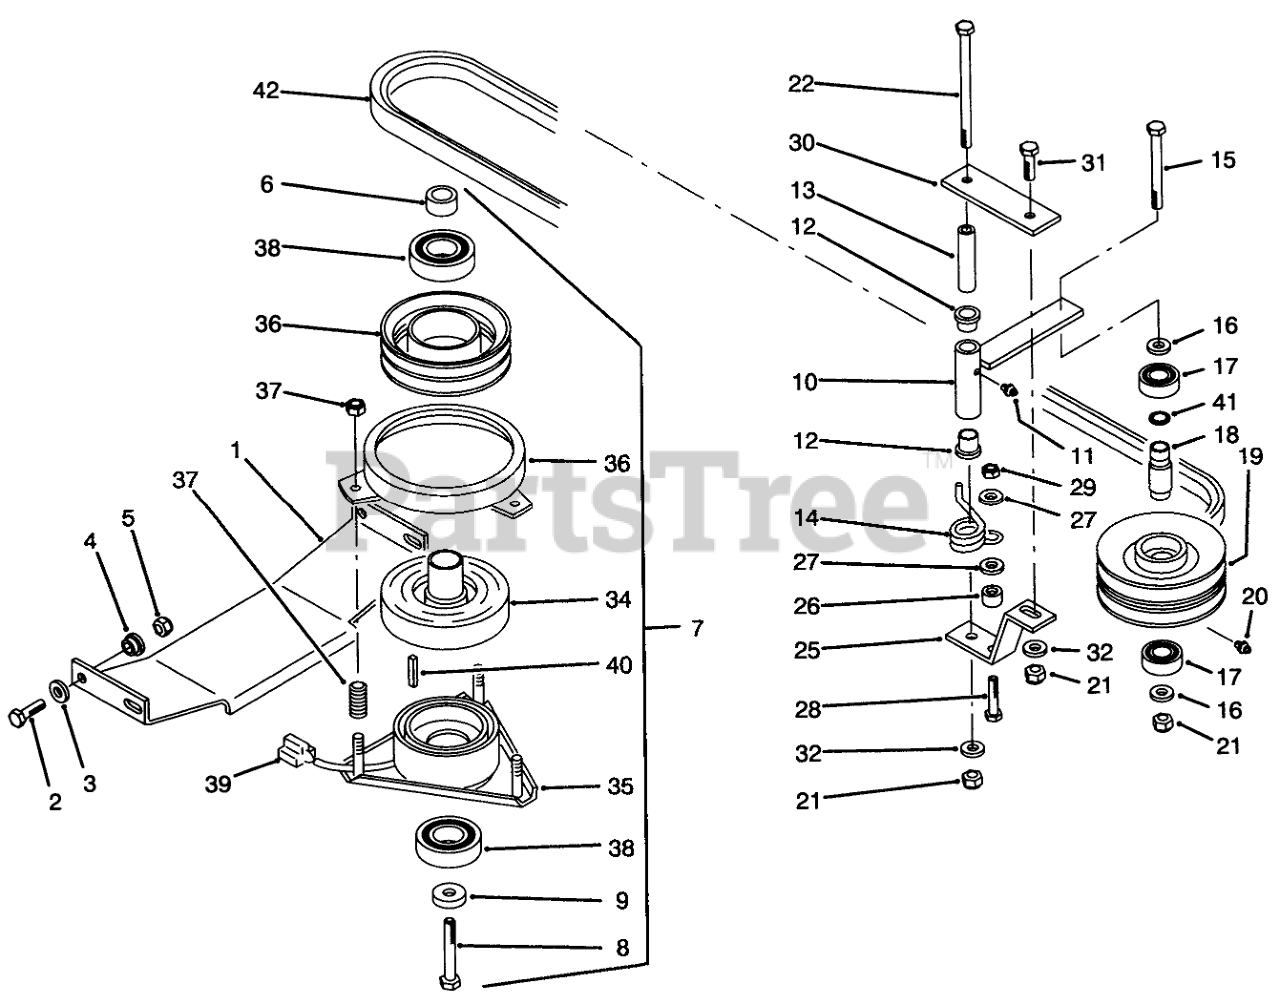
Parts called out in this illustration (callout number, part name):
1	BRACKET CLUTCH ST R
2	SCREW-HH
3	WASHER-PLAIN
4	BUSHING
5	NUT-LOCK, NI
6	SPACER
7	Electric Clutch Assembly (Incl. Ref. #6, 8, 9 & 34-40)
8	SCREW-HH
9	WASHER
10	Arm-Idler
11	Fitting-Grease
12	BUSHING
13	SPACER
14	SPRING-TORSION
15	SCREW-HH
16	Washer
17	BEARING-BALL
18	SPACER-PTO IDLER
19	PULLEY 2- GROOVE
20	FITTING-GREASE
21	NUT-LOCK, NI
22	SCREW-HH
25	Bracket-Idler
26	Spacer
27	WASHER-FLAT
28	SCREW-HH
29	NUT-LOCK, NI
30	Plate
31	SCREW-HH
32	WASHER-FLAT
34	ROTOR ASSEMBLY
35	Field Assembly (Incl. Ref. #38)
36	Armature & Pulley Assembly (Incl. Ref. #38)
37	ACCESS SPRING & NUT
38	BEARING-ELEC CLUTCH
39	CONNECTOR BODY B
41	O RING
42	V-BELT
